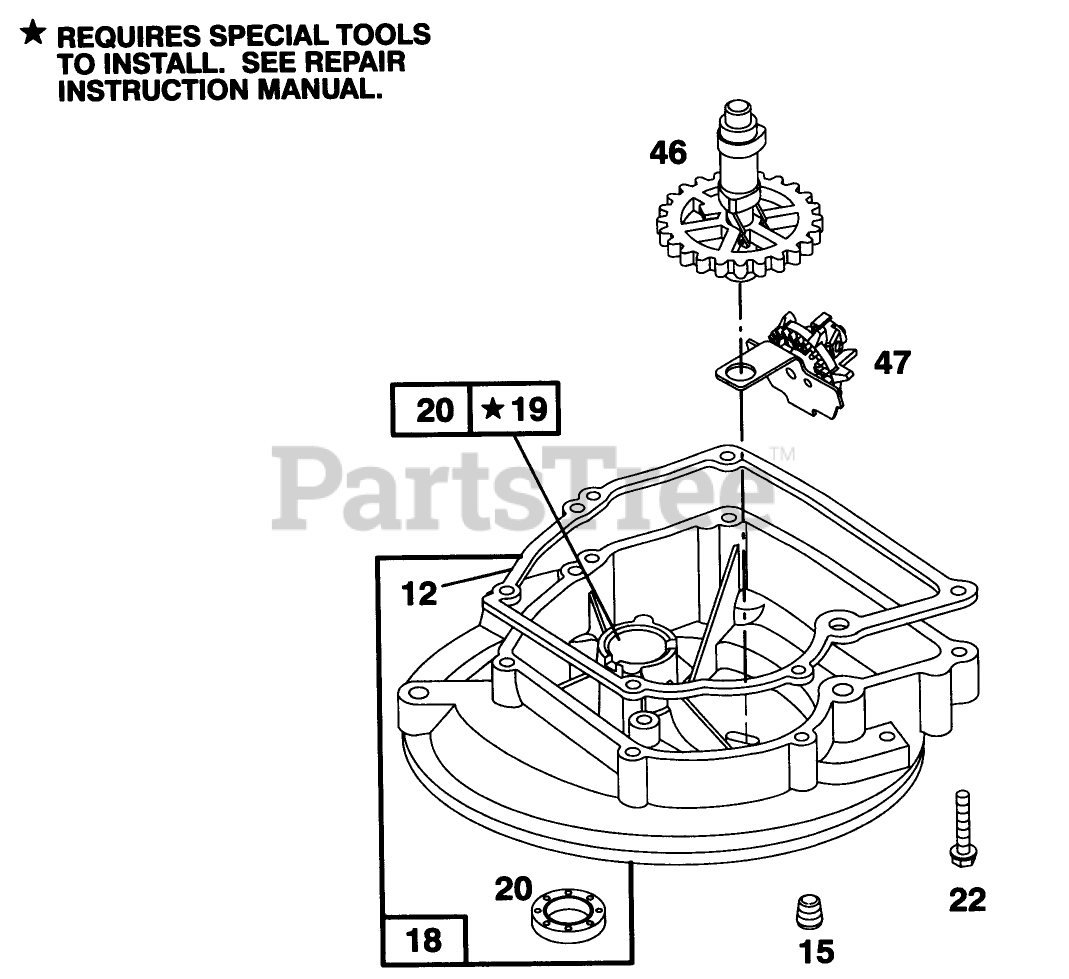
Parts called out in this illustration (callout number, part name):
12	Gasket-Crankcase-.015" thick
15	Plug-Pipe
18	Sump-Oil
19	Bushing-Oil Base
20	Seal-Oil
22	Screw-Mtg. Sem
46	Gear-Cam
47	Oil Slinger Gear and Bracket
